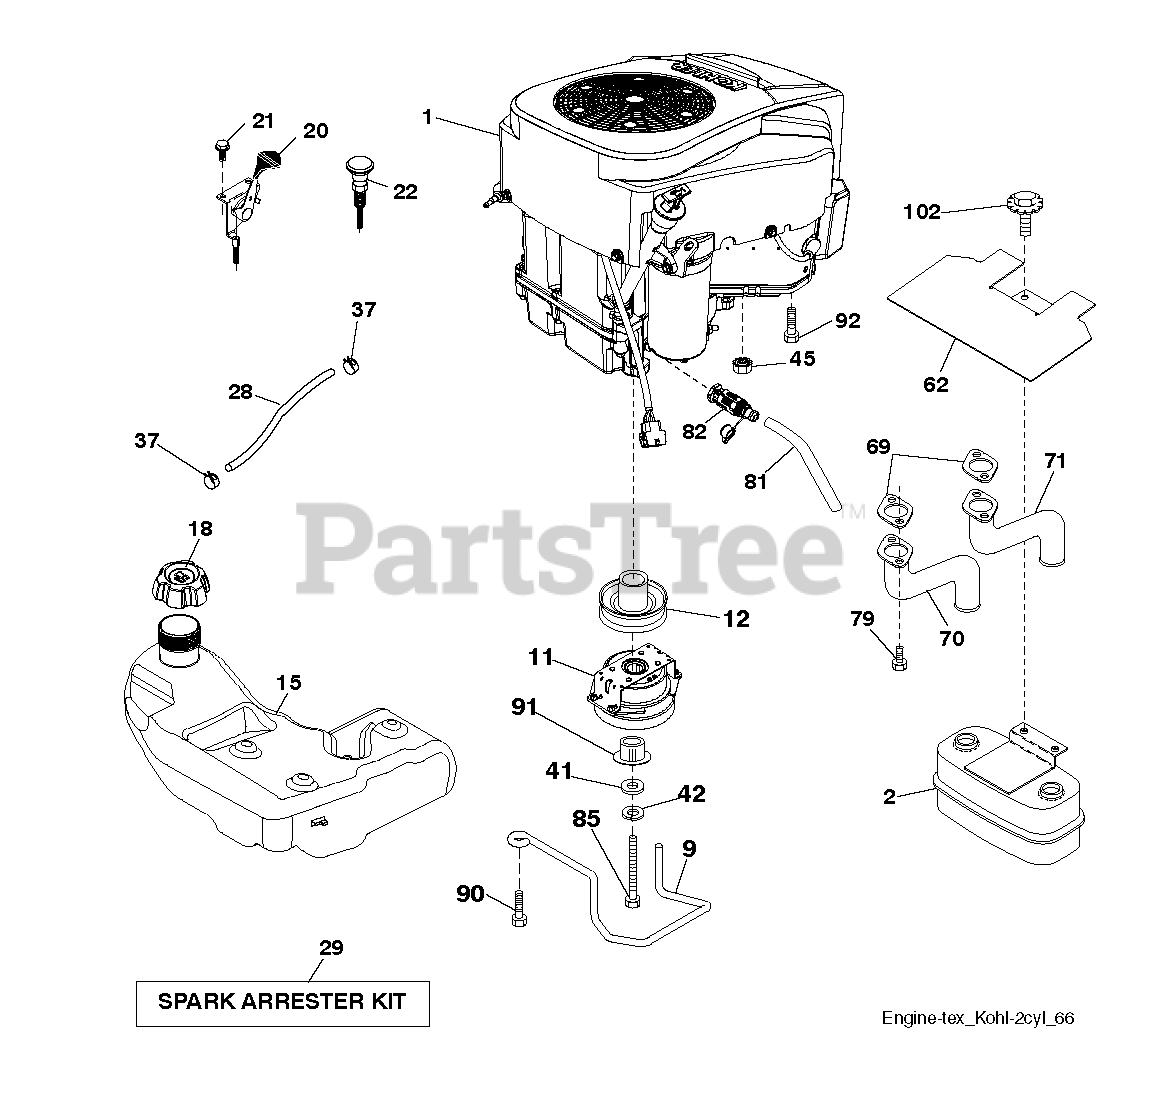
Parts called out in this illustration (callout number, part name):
2	MUFFLER.ASM.TWN.EXTNDED.DFLCTR
9	KEEPER.BELT.ENGINE
11	CLUTCH.OGURA.4.4PD.GT1.5-EH13V
12	PULLEY.ENGINE.ENX
15	TANK.ASSY.3.GAL.EPA
18	Fuel Cap Assembly, 3" Black
20	THROTTLE CONTROL
21	SCREW.#10 X 0.750.BOS (2 2)
22	CONTROL CHOKE
28	LINE.FUEL.64"REAR.EMIS
29	KIT.SPARK ARRESTOR(392390 B&S)
37	HOSE CLAMP
42	LOCKWASHER
45	NUT
62	SHIELD.HEAT.MUFFLER
69	GASKET.EXHAUST.KOHL.CV18-CV26
70	Exhaust Pipe, LH CV18/20
71	Exhaust Pipe, RH CV18/20
79	SCREW.SOCKET HD.5/16-1
81	TUBE, DRAIN OIL ASM.
82	VALUE.OIL.DRAIN
85	Clutch Bolt, 7/16-20 X 3.5 Gr 5 24Hr
90	SCREW 3/8-16X1
91	BUSHING.1.375OD
92	SCREW 3/8-16X1
102	SCREW
